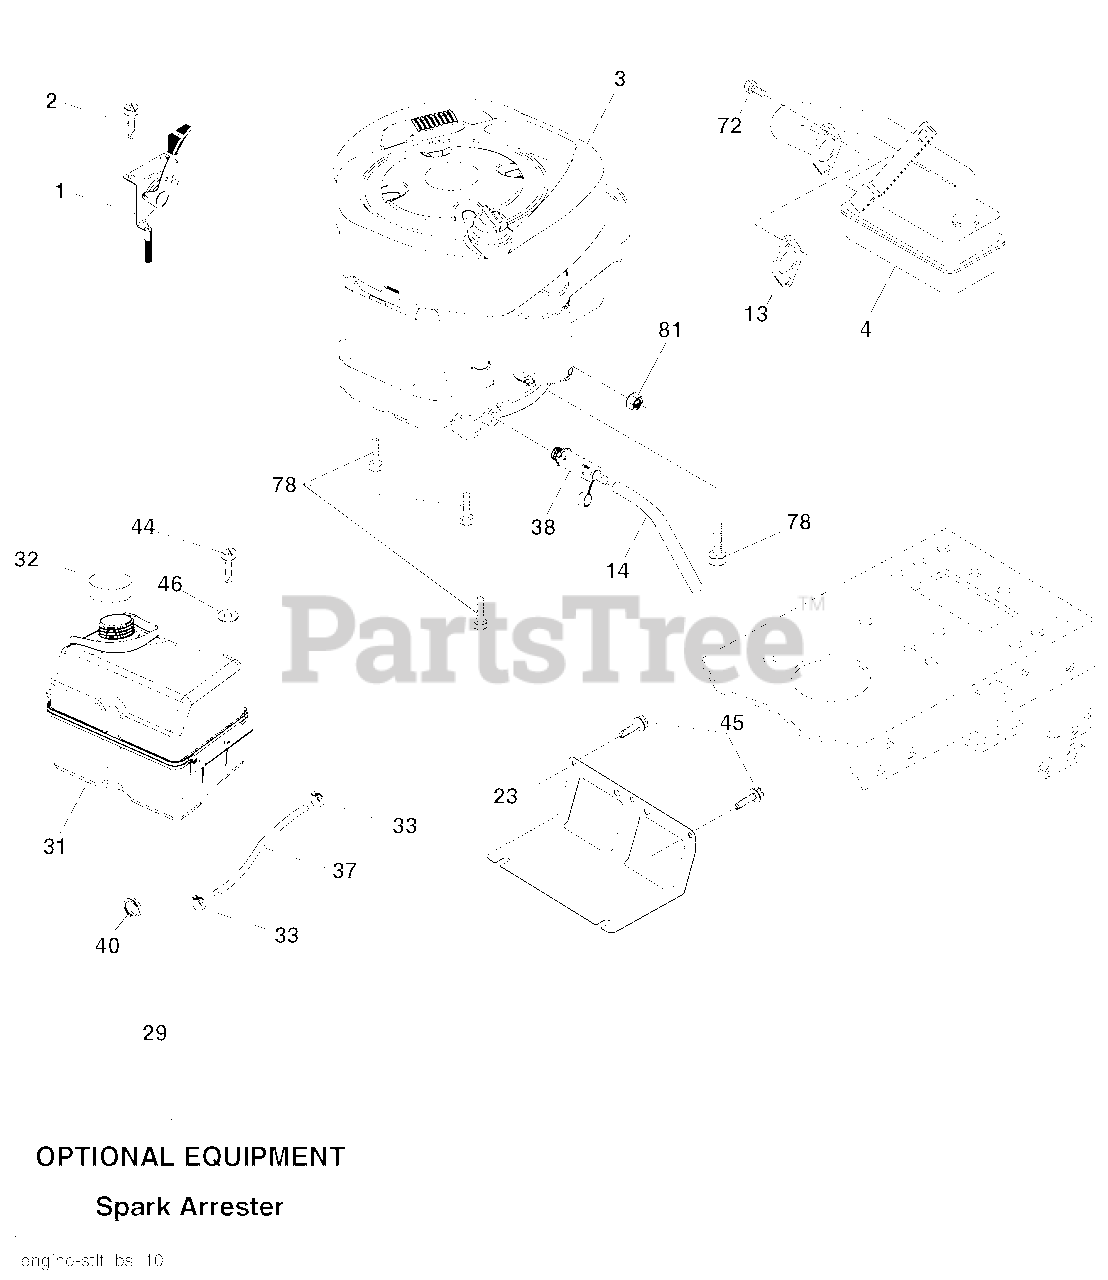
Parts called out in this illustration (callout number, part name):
1	Control Th/ch Flag
2	Screw Hex Thd Cut 1/4-20 x 1/2
4	Muffler Exhaust B&S
13	Gasket Eng 1 313 Id Tin Plated
14	Tube Drain Oileasy
23	Shield BRN/DBR Guard
29	Kit Spark Arrestor (Flat Scrn)
31	Tank Fuel Front
32	Cap Asm Fuel
33	Clamp Hose
37	Line Fuel 20"
38	Plug Drain Oil
40	GROMMET T
44	Screw Thdrol 1/4-20 x 3/4
45	Screw Hex Wsh Thdrol 3/8-16
46	Washer 9/32 x 7/8 x 16 Ga.
72	Screw Socket Hd 5/16-18 x .75
78	Screw 3/8-16 x 1-1/4
81	Nut Keps Hex 1/4-20 unc
